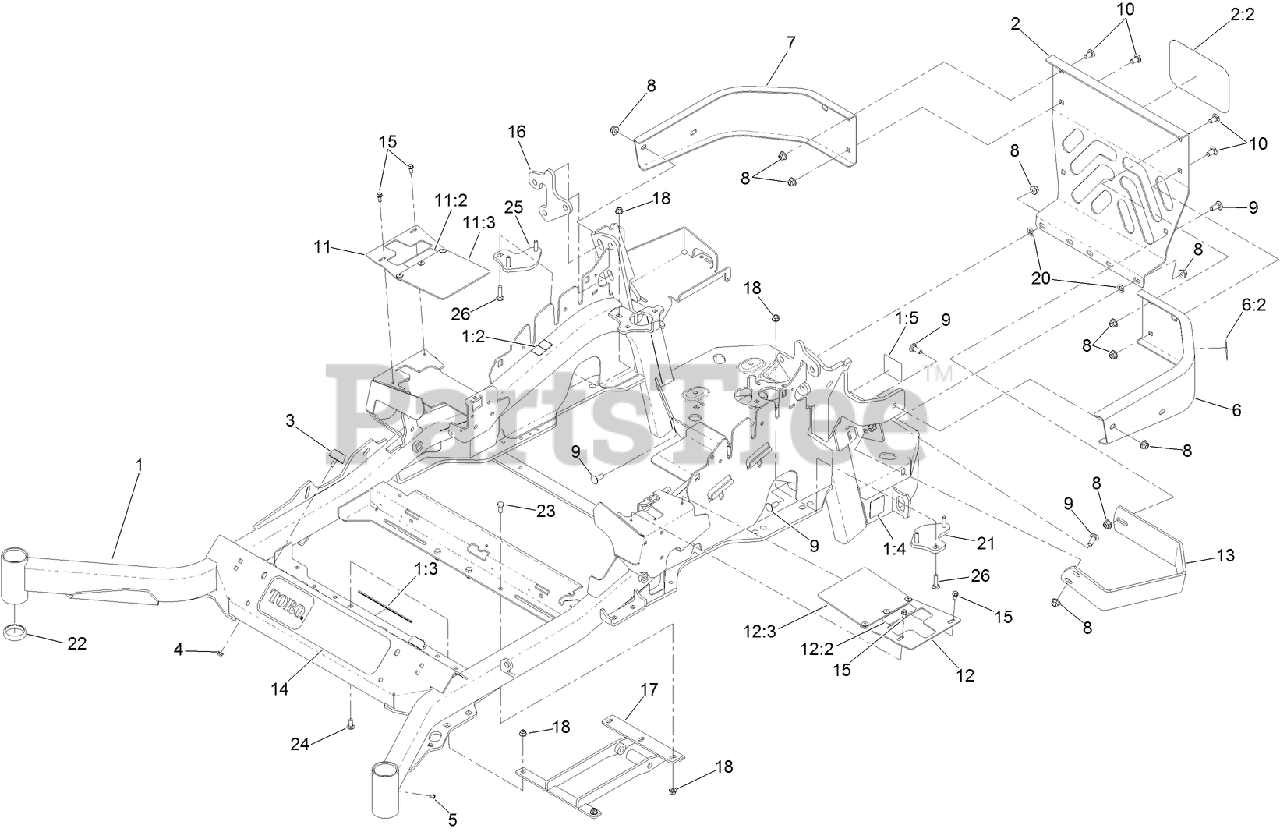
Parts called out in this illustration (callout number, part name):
1	MAINFRAME ASM
1:2	DECAL-WARNING
1:3	DECAL-DANGER
1:4	DECAL-HAZARD, PINCHED FINGER
1:5	DECAL-ARRESTOR, SPARK
2	REAR GUARD ASM
2:2	DECAL
3	BUMPER
4	NUT-HF
6	LH BUMPER ASM
6:2	DECAL-WARNING
7	BUMPER-RH
8	NUT-HF, NI
9	SCREW-CARR
10	SCREW-CARR
11	RH MOTION CONTROL COVER ASM
11:2	DECAL-CONTROL, MOTION
11:3	FLAP-RUBBER
12	LH MOTION CONTROL COVER ASM
12:2	DECAL-CONTROL, MOTION
12:3	FLAP-RUBBER
13	GUARD-MUFFLER
15	SCREW-HWH
16	PLATE-MOUNT, SHOCK
17	MOUNT-LOWER
18	NUT-HF, NI
20	NUT-PUSH
21	LH PLATE ASM (W/STUDS)
22	CUP-BEARING
23	SCREW-HH
24	SCREW-CARR
25	RH PLATE ASM (W/STUDS)
26	SCREW-CARR
